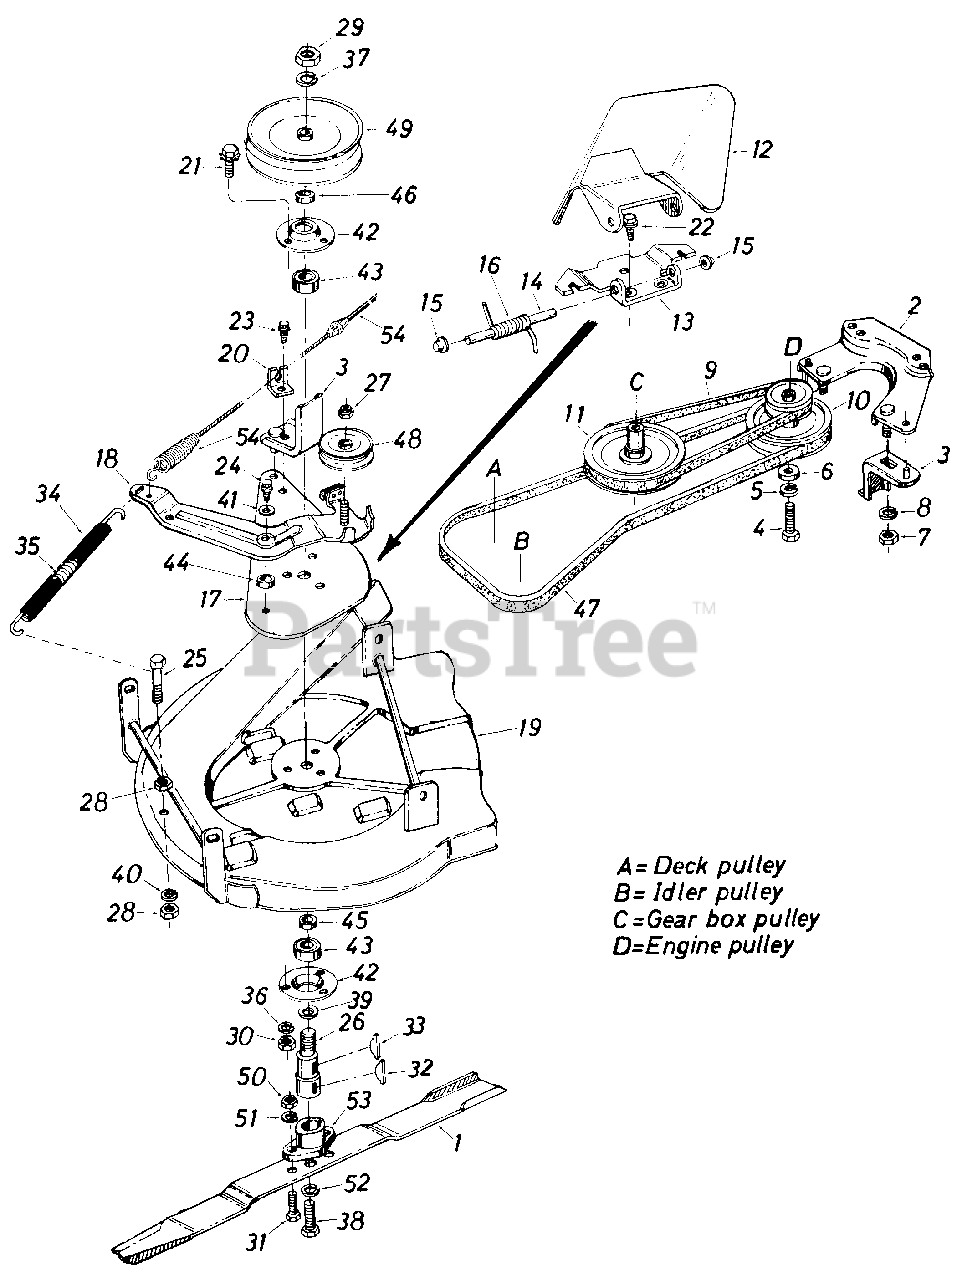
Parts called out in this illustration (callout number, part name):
1	26" Blade
2	Belt Guard Cup Ass'y.
3	Belt Keeper Ass'y.
4	Hex Bolt 3/8-24 x 1.00" Lg.
5	L-Wash. 3/8" I.D.
6	Fl-Wash. .406" I.D. x 1.25" O.D.
7	Hex Nut 5/16-18 Thd.
8	L-Wash. 5/16" I.D.
9	3V-Belt 28" Lg.
10	Double Pulley
11	3/8" V-Pulley .502" I.D. x 6.5" O.D.
12	Chute Cover Ass'y. Comp.
13	Adapter Plate
14	Hinge Pin
15	Cap Speed Nut 1/4" Rod
16	Torsion Spring
17	Deck Belt Guard Plate
18	Deck Idler Brkt. Ass'y.
19	26" Deck Ass'y.
20	Cable Support Brkt.
21	Hex Sems Bolt 5/16-18 x 1.00" Lg.
22	Hex Wash. S-Tap Scr. 1/4-20 x.50" Lg.
23	Hex Wash. Hd. B-Tap Scr. 5/16-18 x .50" Lg.
24	Hex L-Bolt 5/16-18 x 1.00" Lg.
25	Hex Bolt 1/4-28 x 1.50" Lg.
26	Blade Spindle
27	Hex Ins. L-Nut 3/8-24 Thd.
28	Hex Cent. L-Nut 1/4-28 Thd.
29	Hex Jam Nut 5/8-11 Thd.
30	Hex Nut 5/16-18 Thd.
31	Hex Bolt 5/16-24 x 1.00" Lg. (Grade 8)
32	#6 Hi-Pro Key 5/32 x 5/8" Dia.
33	#61 Hi-Pro Key 3/16" x 5/8" Dia.
34	Plastic Tube .52" I.D. x 7.0" Lg.
35	Ext. Spring .50" O.D. x 5.2" Lg.
36	L-Wash. 5/16" I.D.
37	L-Wash. 5/8" I.D.
38	Hex Bolt 3/8-24 x 1.50" Lg. (Grade 5)
39	Bearing Shield
40	L-Wash. 1/4" I.D.
41	Fl-Wash. .330" I.D. x 1.25" O.D. x .120
42	Bearing Housing
43	Ball Brg. .787" I.D. x 1.85" O.D.
44	Spacer.315" I.D. x .75" O.D. x.37" Lg.
45	Spacer.836" I.D. x 1.01" O.D. x .320" Lg.
46	Spacer.630" I.D. x 1.135" O.D. x .195" Lg.
47	"V"-Belt-A Sec. x 59.0" Lg.
48	"V"-Idler 3.06" O.D.
49	5/8" V-Pulley .625" I.D. x 7.0" O.D.
50	Hex Nut 5/16-24 Thd.
51	L-Wash. 5/16" I.D.
52	L-Wash. 3/8" I.D.-Heavy Duty
53	Blade Adapter Kit
54	Clutch Cable-56.0"
